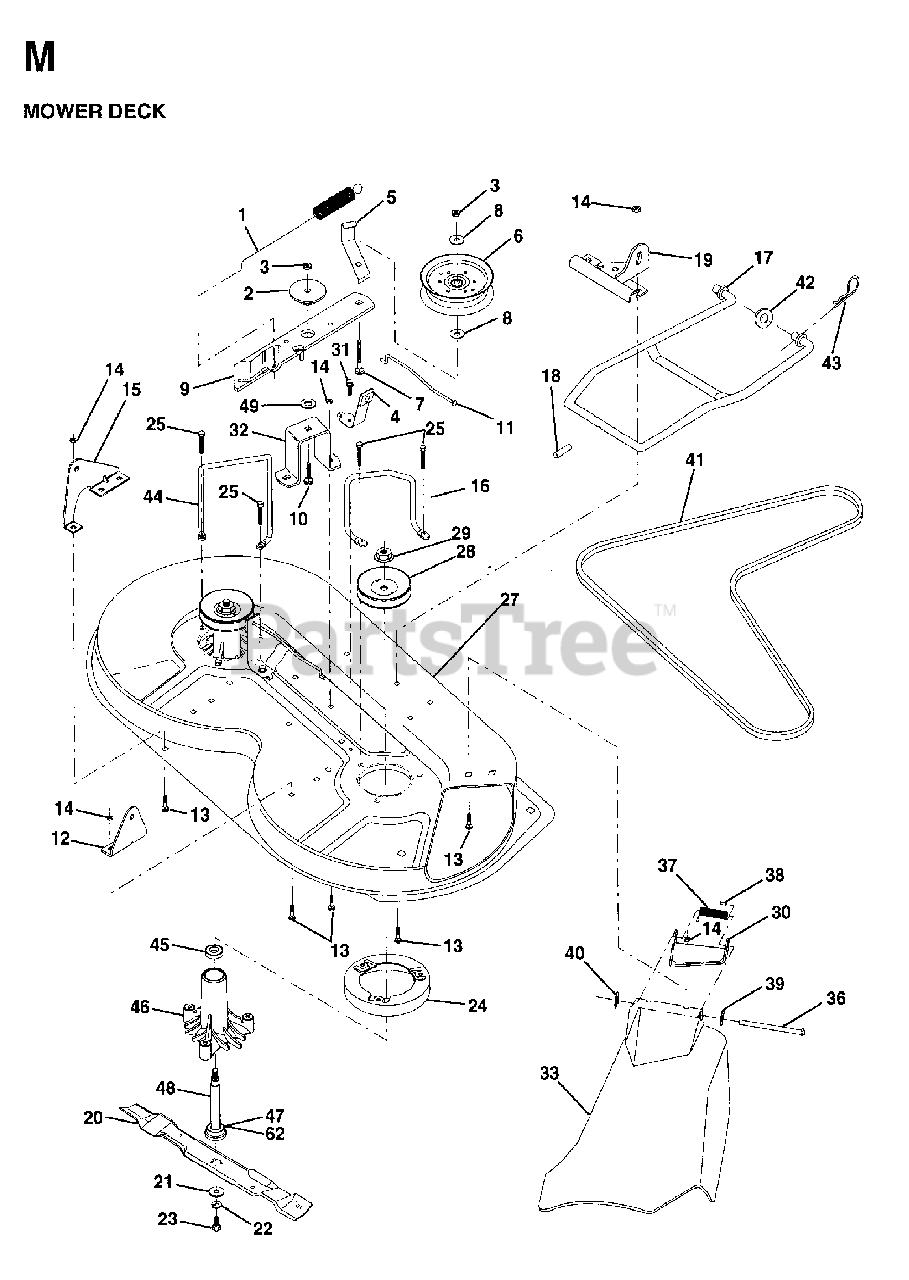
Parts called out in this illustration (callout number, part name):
1	SPRING-MOWER CLUTCH
2	SPACER RETAINER
3	LOCKNUT
4	BRAKE ASSEMBLY
5	IDLER BELT GUIDE
6	PULLEY IDLER
7	BOLT
8	WASHER
9	IDLER ARM ASSY
10	BOLT.3/8-14X1.25
11	BRAKE ROD
12	BRKT LIFT REAR
13	BOLT
14	LOCKNUT
15	BRKT LIFT REAR LH
16	BELT KEEPER
17	MOWER LINK STABILIZER
18	PIN GROOVE
19	BRKT LINK STABILIIZER
21	WASHER.BLADE
22	LOCKWASHER
23	BLADE BOLT
24	STRIPPER
25	SCREW
27	MOWER HOUSING
28	PULLEY, MANDREL
29	NUT
30	BRACKET ASM DEFLECTOR
32	SUPT,IDLER ARM
33	DEFLECTOR
36	HINGE ROD
37	SPRING TORSION
38	CAP-SLEEVE LT
39	WASHER
40	NUT PUSH M
42	WASHER
43	SPRING RETAINER
44	KEEPER LH
46	HSG MANDREL
47	BEARING
48	SHAFT ASM VENT
49	HARDENED WASHER
62	WASHER FELT
